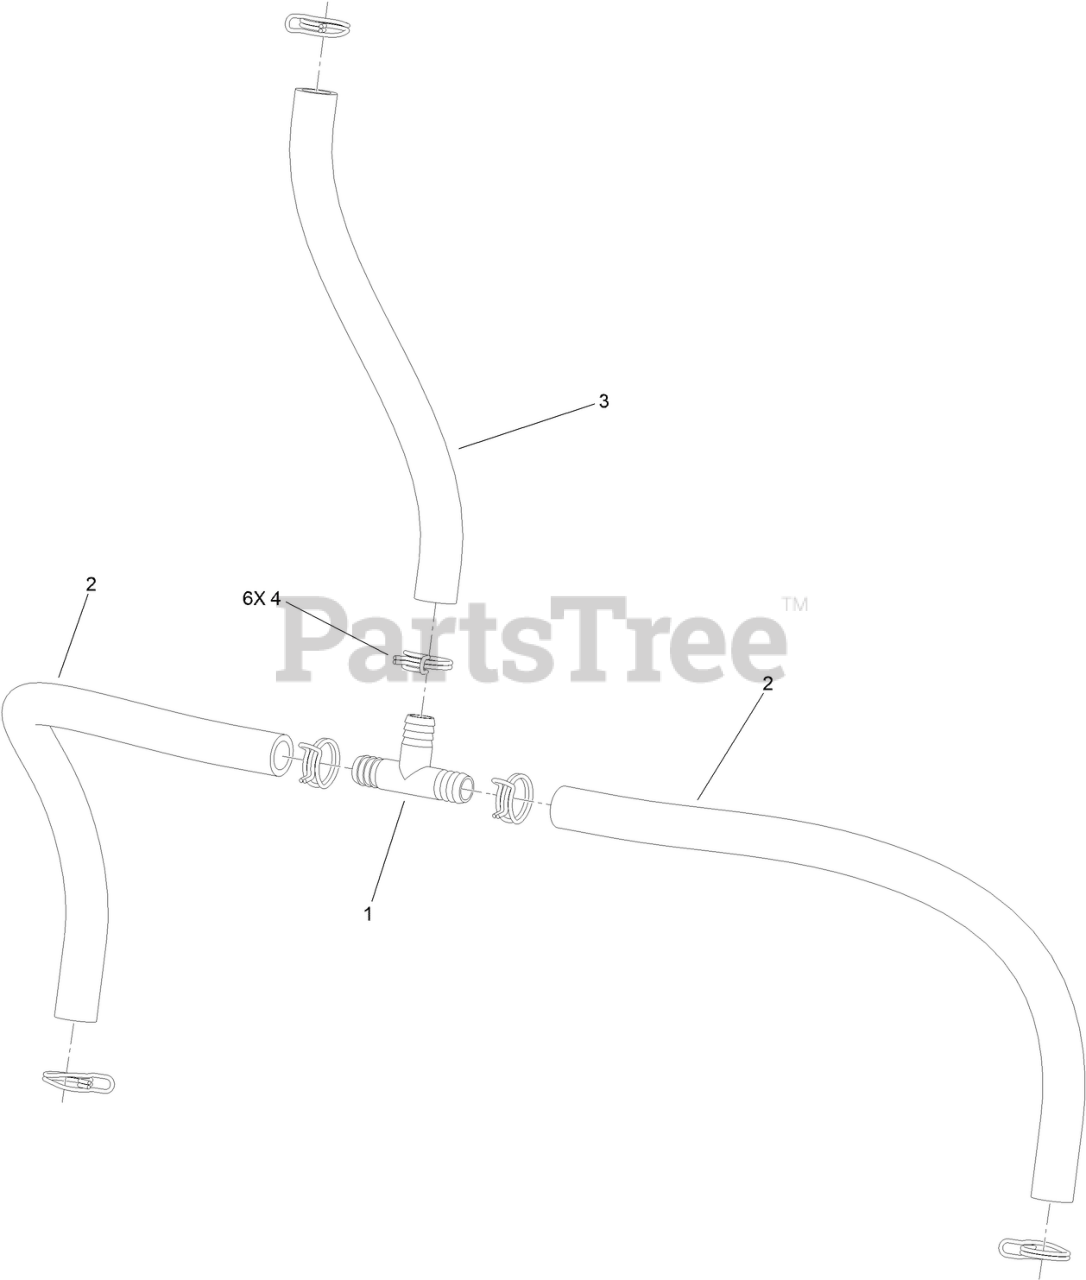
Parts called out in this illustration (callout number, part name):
2	HOSE-LOWER, 5/8 ID
3	HOSE-UPPER, 5/8 ID
4	CLAMP-HOSE
